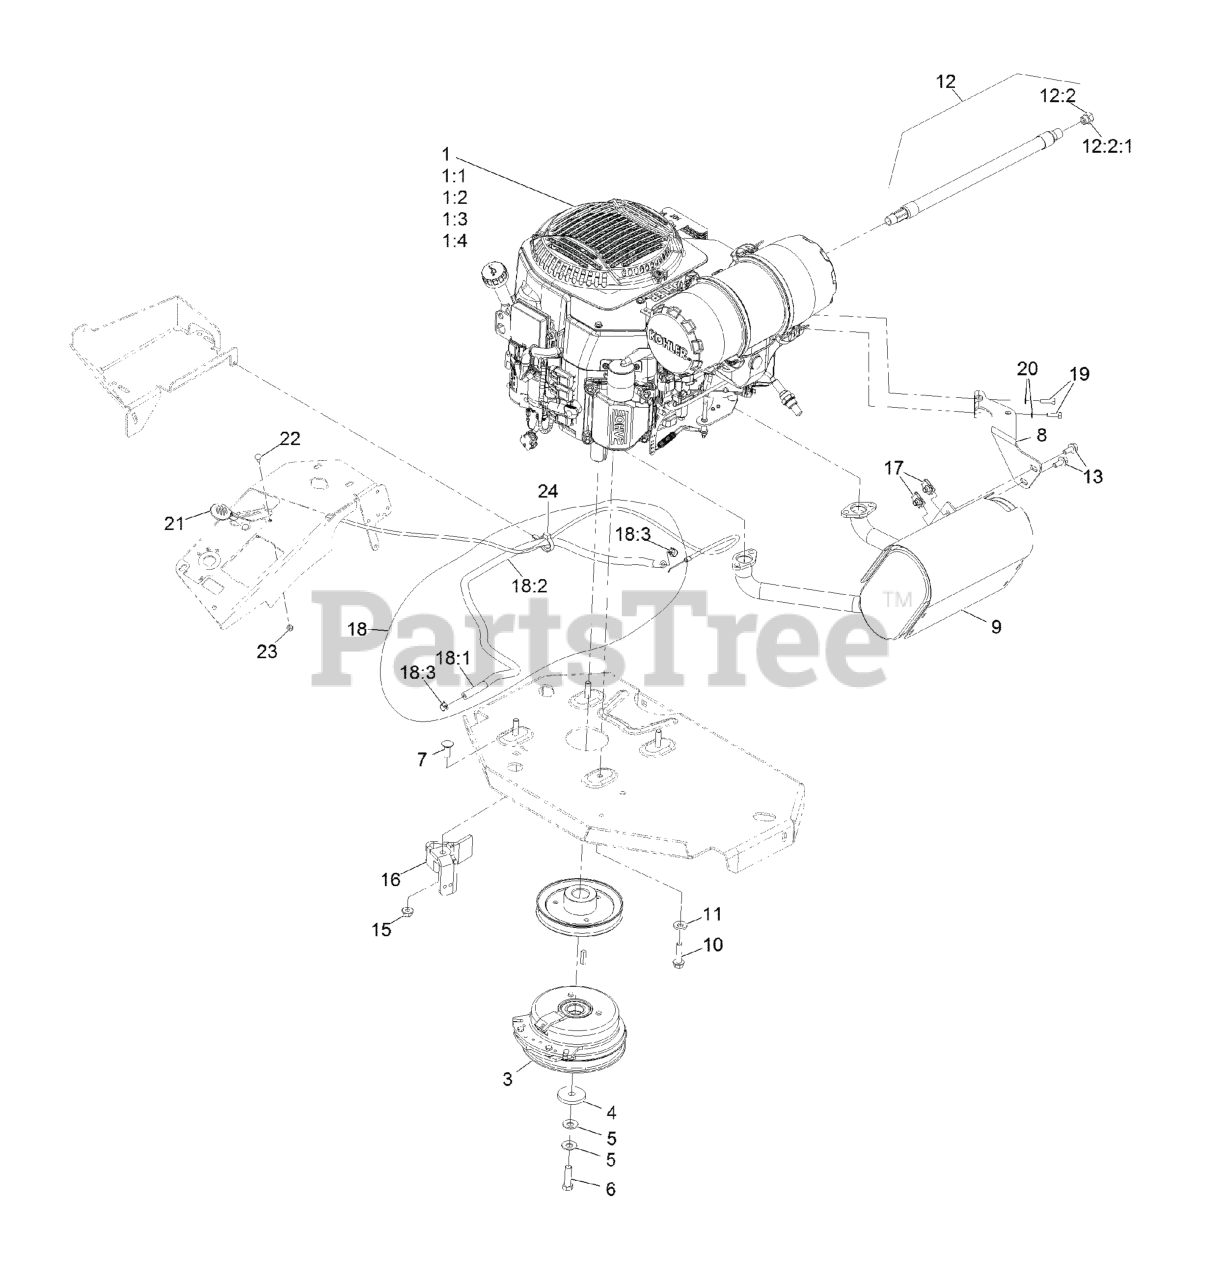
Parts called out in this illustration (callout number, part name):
1:1	Kohler 52 050 02-S Engine Oil Filter
1:2	Kohler 25 083 01-S Engine Air Filter
1:3	Kohler 25 083 04-S Safety Filter
1:4	Kohler 25 050 42-S Fuel Filter
3	CLUTCH KIT
4	WASHER-CLUTCH
5	WASHER-SPRING
6	SCREW-HH 7/16-20 X 1 1/2 W/LOCTITE
7	SCREW-CARR
8	MUFFLER BRACKET KIT
9	MUFFLER KIT
10	SCREW-HWH
11	WASHER-BELLEVILLE
12	OIL DRAIN HOSE ASM
12:2	PLUG-HH
12:2:1	O-RING
13	SCREW-HHF
15	NUT-HF, NI
16	CLUTCH-ANCHOR
18	FUEL LINE ASM
18:1	HOSE-FUEL
18:2	SLEEVE-THERMAL
18:3	CLAMP-HOSE
19	SCREW-HH M6-1 X 20Mm W/Patch
20	WASHER-SPRING
21	ASM,THROTTLE CABLE
22	BOLT-CARR
23	NUT-LOCK, NI
24	CLAMP-HOSE
